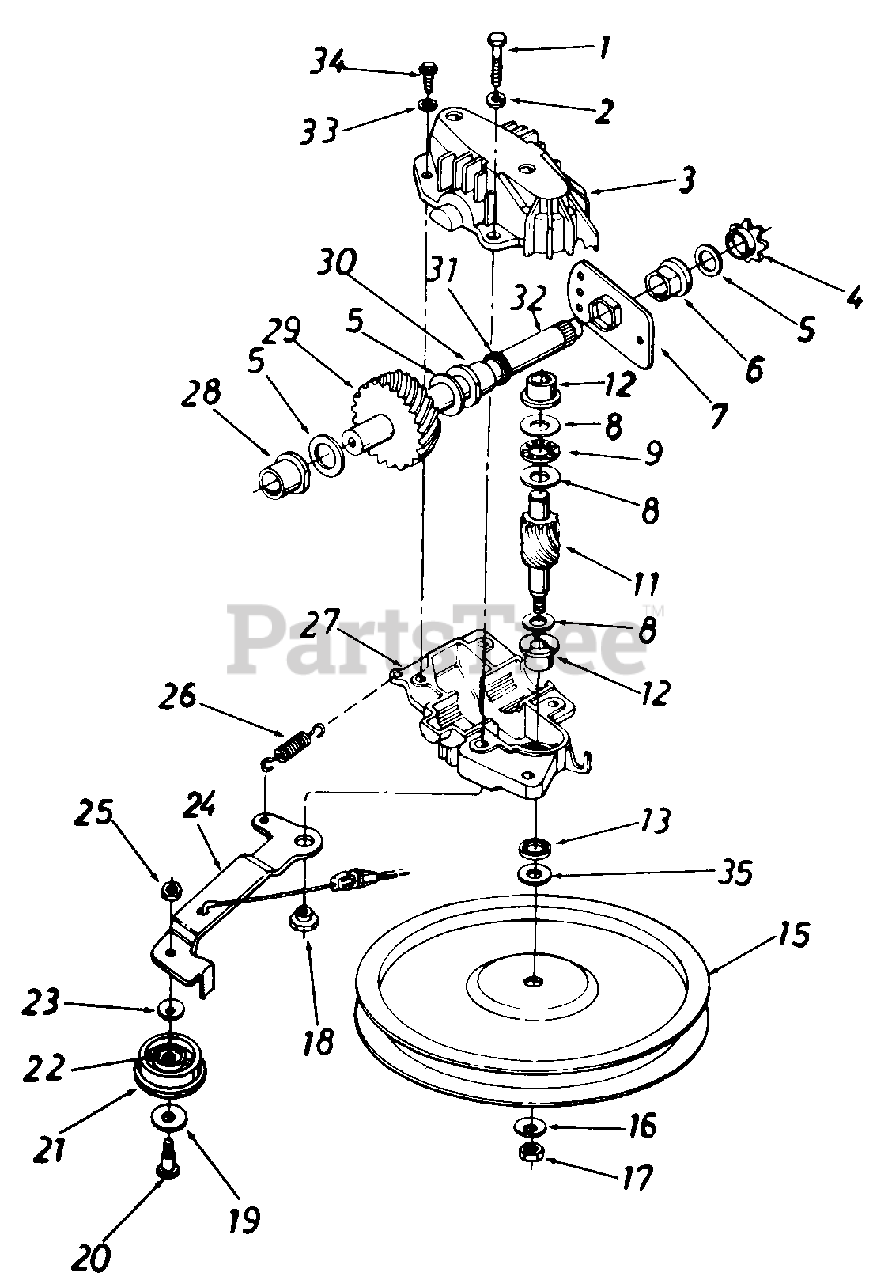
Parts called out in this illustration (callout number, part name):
1	Hex Bolt 1/4-20 x 1.25" Lg. w/Patch
2	L-Wash. 1/4" I.D.
3	Upper Hsg. Half
4	#48 Sprocket 7 Tooth x 1/2 Pitch
5	Fl-Wash. 5/8" I.D. x .030
6	Hex Flange Brg. .631" I.D.
8	Thrust Wash. .382" I.D. x .70" O.D.
9	Thrust Bearing .375" I.D. x .812" O.D.
11	11 Tooth Pinion Shaft
12	Flange Bearing
13	Oil Seal
15	Fl-Pulley 5.06" O.D.
16	Bell-Wash. .265" I.D. x .75"
17	Hex L-Nut 1/4-28 L.H. Thd.
18	Shld. Spacer .375" Dia. x .170
19	Fl-Wash. .390" I.D. x 1.0"
20	Shld. Bolt .375" Dia. x .40"
21	Fl-Idler Plastic 1.50" Dia.
22	Needle Brg. .375" x .31
23	Bell-Wash. .265" I.D. x 75"
24	Idler Brk't. Assy.
25	Hex Patch L-Nut 1/4-28 Thd.
26	Extension Spring 1.12" Lg.
27	Lower Hsg. Half
28	Flange Bearing .566 Dia.
29	33 Tooth Helical Gear
30	Flange Bearing .629 Dia.
31	Oil Seal .625 Dia.
32	Gear Sprocket Shaft
33	L-Wash. #10 I.D.
34	Hex B-Tap Scr. #10 x .62"
35	Hex Washer .26" x .88"
